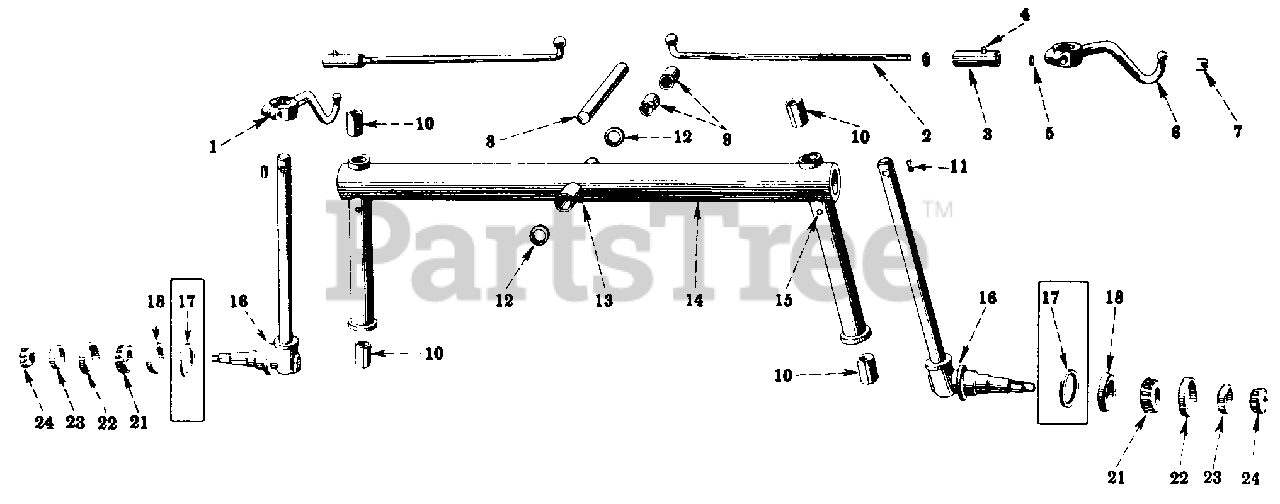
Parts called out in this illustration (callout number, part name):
1	ARM, STEERING KNUCKLE LH
3	END, TIE ROD ADJUSTABLE
4	FITTING, 1/4-28 NS TAPER STR LUB
5	SEAT, TIE ROD BALL
6	ARM, STEERING KNUCKLE RH
7	SEAT, TIE ROD ADJUSTABLE BALL
8	SHAFT, FRONT AXLE PIVOT
9	BUSHING, FRONT AXLE PIVOT
10	BUSHING, STEERING KNUCKLE POST TUBE
11	KEY, .25 X .88 SQ PARALLEL
12	WASHER, FRONT AXLE PIVOT THRUST
13	FITTING, 1/4-28 NS TAPER STR LUB
14	AXLE, FRONT
15	FITTING, 1/4-28 NS TAPER STR LUB
16	KNUCKLE W/OIL SEAL, IH-350769-R91 AND WASHER, IH-350768-R1, STEERING
17	WASHER, FRONT WHEEL FELT
18	SEAL, FRONT WHEEL OIL
21	BEARING ASSY, FRONT WHEEL INNER CONE
22	BEARING, FRONT WHEEL INNER CUP
23	BEARING, FRONT WHEEL OUTER CUP
24	BEARING ASSY, FRONT WHEEL, OUTER CONE
